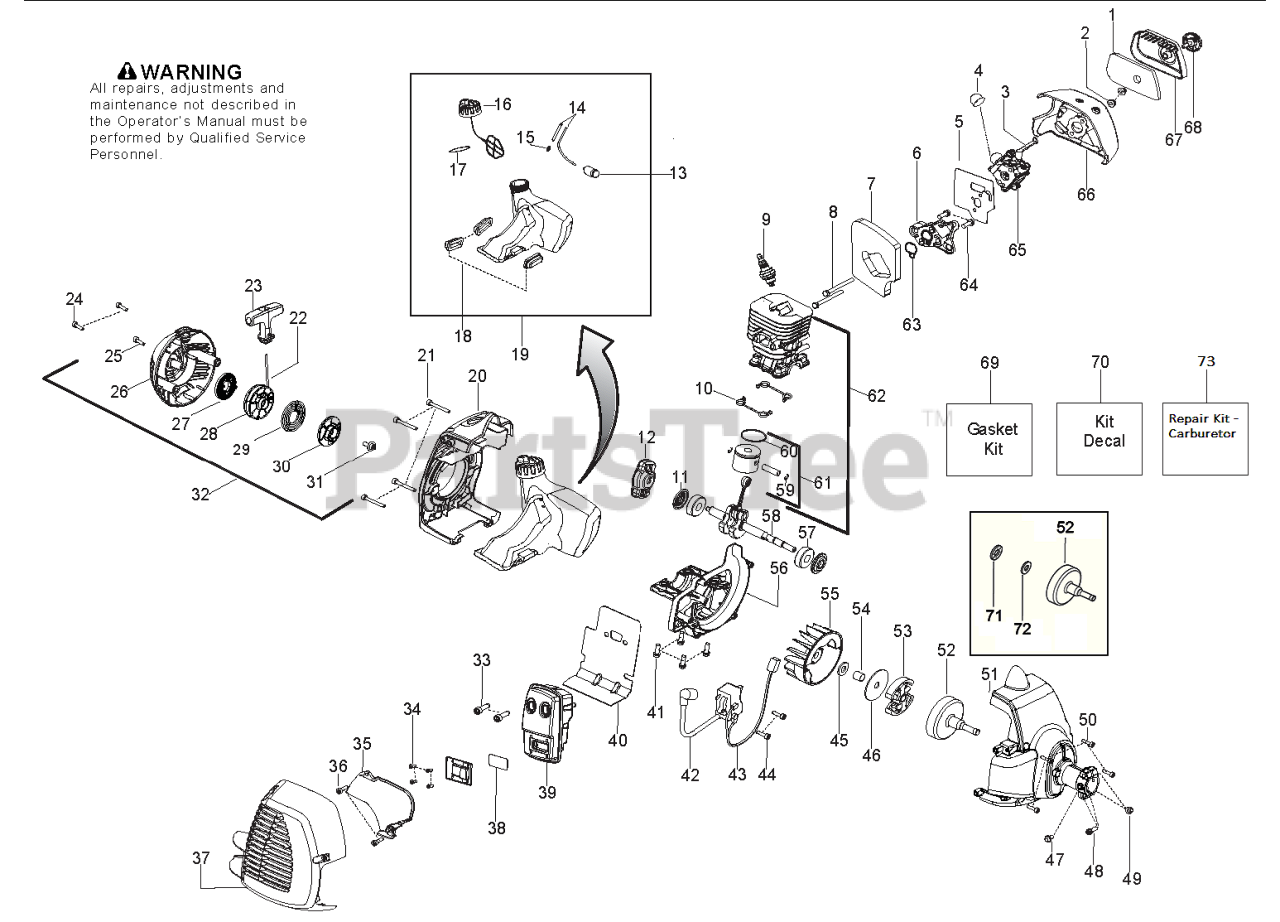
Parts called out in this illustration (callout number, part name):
1	FILTER AIRBOX
3	CHOKE LEVER
4	PURGE BULB ZAMA
5	KIT GASKET 28CC
6	CARB ADAPTOR
7	KIT GASKET 28CC
8	BOLT CARB ADAPTOR
9	Plug - Spark (RCJ-8Y)
10	KIT GASKET 28CC
11	KIT GASKET 28CC
12	STARTER PAWL BRIDGE
13	ASSY FUEL PICKUP PRE FLUSHED
14	KIT-LINE(FUEL)
15	FUEL LINE FITTING
16	ASSY-CAP W/RETAINER
17	KIT GASKET 28CC
18	ISOLATOR FUEL TANK
19	KIT FUEL TANK HVA
20	REAR SHROUD ORANGE
22	KIT ROPE
23	STARTER HANDLE
24	SCREW M5-0.8X30MM
25	SCREW M4 X 1.75 PT 16MM
26	HOUSING STARTER
27	KIT STARTER SPRING
28	KIT PULLEY/SPRING
29	DRIVER SPRING
30	PULLEY STARTER DRIVE
32	ASSY STARTER HSG HVA
33	BOLT MUFFLER
34	SCREW-6-19X5/16PLAST PA
35	SHIELD HEAT
36	SCREW M4 X 1.75 PT 16MM
37	KIT MUFFLER GUARD HVA
38	KIT SPARK ARRESTOR SCREEN
39	KIT MUFFLER W/CATALYST
40	KIT GASKET 28CC
41	SCREW-M5-0.8 X 25MM(TAP)
42	IGNITION MODULE MBU-7
43	ASSY MODULE LEAD WIRE
44	SCREW M4 X .70 TT 16MM
45	WASHER CLUTCH
46	WASHER-CLUTCH
47	SCREW-10-14 X 1/2 PLASTITE
48	SCREW-10-24 X 1" (UNC)
49	LOCKNUT-HEX 10-24
50	SCREW M4 X .70 TT 16MM
51	ASSY FAN HOUSING HVA 1"
52	ASSY-CLUTCH DRUM
52	KIT DRUM CLUTCH ASSY
53	ASSEMBLY CLUTCH
54	SPACER FLYWHEEL
56	CRANKCASE CAST 128
57	BEARING RADIAL BALL (6201)
58	CRANKSHAFT
59	WRIST PIN RET.
60	RING PISTON
61	KIT - PISTON
62	KIT PISTON CYL
63	KIT GASKET 28CC
64	SCREW-M5-0.8 X 25MM(TAP)
66	AIRBOX HVA 128 HUSKY GRAY
67	COVER-AIR BOX
68	KNOB ASSY AIRBOX COVER
69	KIT GASKET 28CC
71	BEARING THRUST
72	WASHER THRUST
73	Gaskets
73	GASKET
